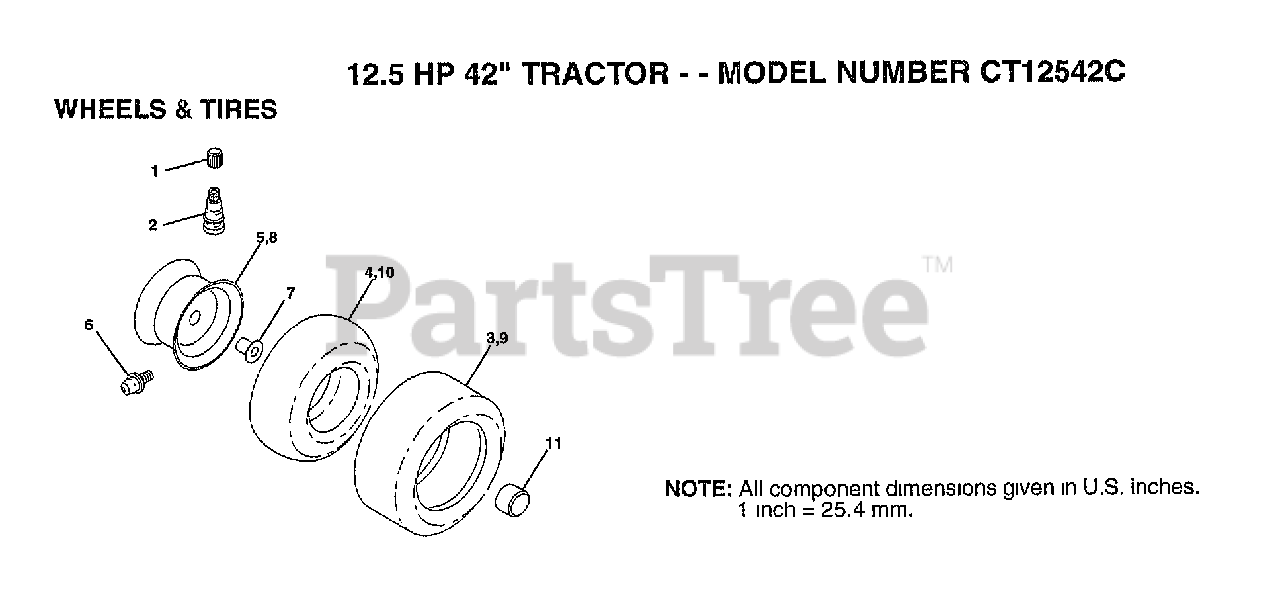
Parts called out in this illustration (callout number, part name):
1	VALVE CAP
2	VALVE STEM LT
4	TUBE.5.3/4.5/6
6	FITTING LT
7	"FLANGE, BEARING"
10	TUBE.18X9.5-8
11	HUB CAP
